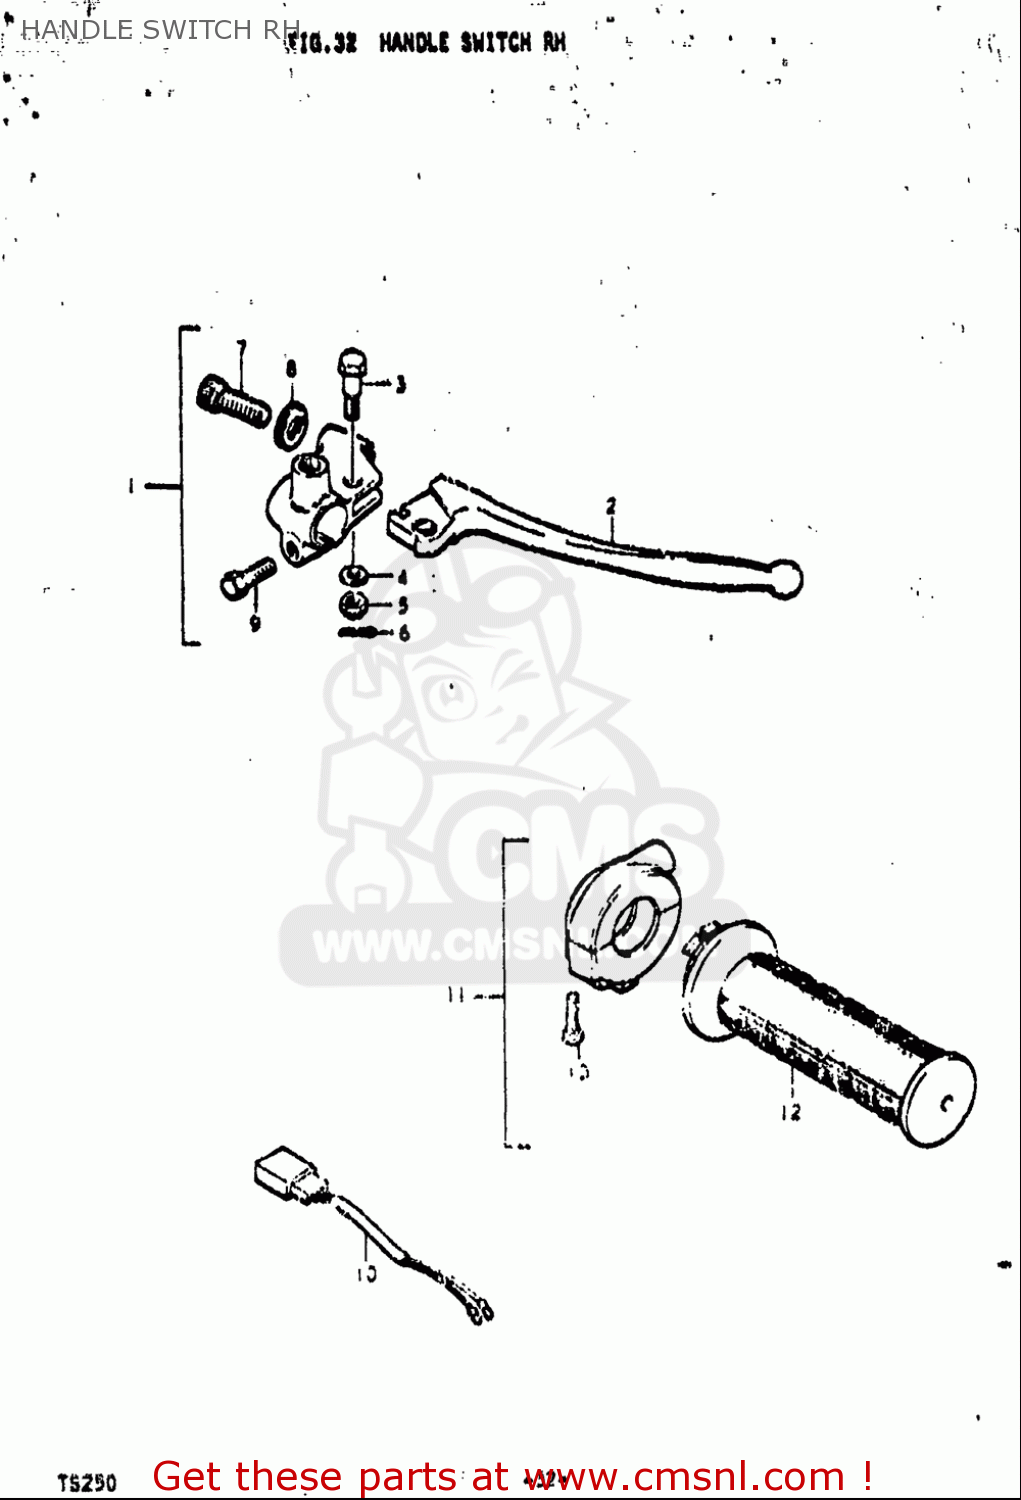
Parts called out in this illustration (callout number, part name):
1	BRAKE LEVER & SWITCH ASSY
2	LEVER,BRAKE
3	BOLT,LEVER PIVOT
4	WASHER,LOCK
5	NUT,LEVER FITTNG
6	PIN 16X20
7	ADJUSTER,CABLE
8	NUT,CABLE ADJUSTER
9	BOLT
10	LEAD WIRE
11	GRIP ASSY,THROTTLE
12	GRIP,THROTTLE
13	SCREW
